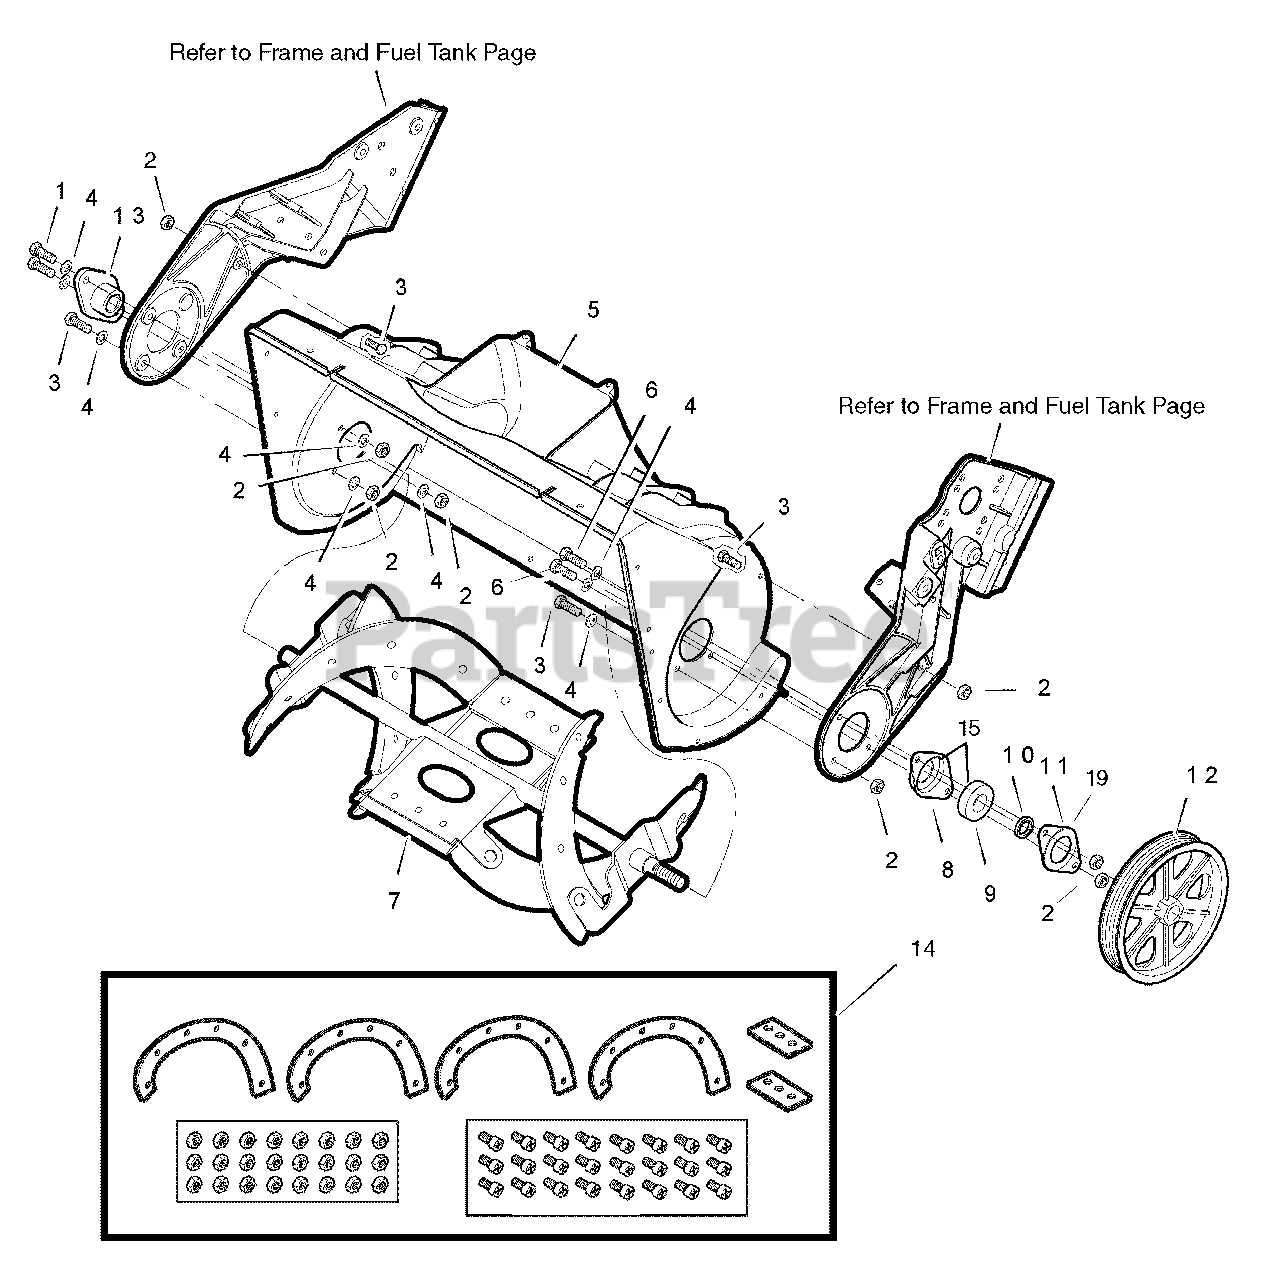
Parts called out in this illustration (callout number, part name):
1	SCREW, 1/4-20 x 1.00
2	NUT, Hex 1/4-20
3	SCREW, 1/4-20 x 3/4
4	WASHER, Flat
5	HOUSING ASSEMBLY, Auger
6	SCREW, 1/4-20 x 5/8
7	AUGER, Assembly, 22"
8	RETAINER, Bearing
9	BEARING, Ball
10	SLEEVE, Spacer
11	PLATE, Bearing Retainer
12	PULLEY, Auger Drive V6
13	BEARING, Flange
14	KIT, Auger Flight
15	assy, Plate & Bearing
19	RETAINER, Bearing
